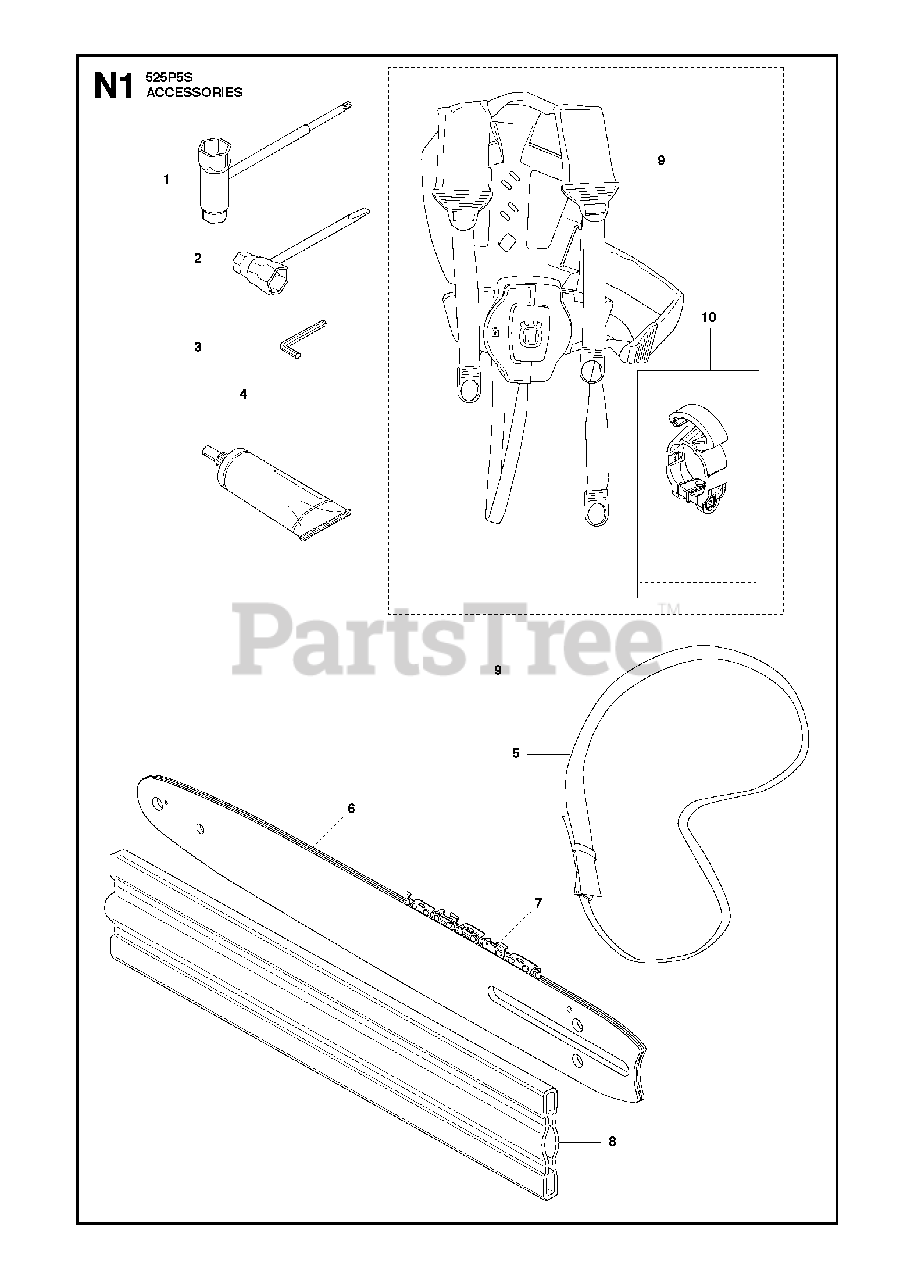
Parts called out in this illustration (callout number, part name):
1	COMBINATION WRENCH TORX
2	COMBI TOOL
4	GREASE
5	HARNESS WITHOUT HOOK
6	Guide Bar, 10" HL280-40 3/8" .050
6	Guide Bar, 12" Hl280-45 3/8 .050
7	Saw Chain, 10" H37-40 3/8 Mini, .050
7	Saw Chain, 12" H3745 38.050
9	BALANCE FLEX HARNESS
10	ACCESSORY BAG HARNESS HOOK 525
